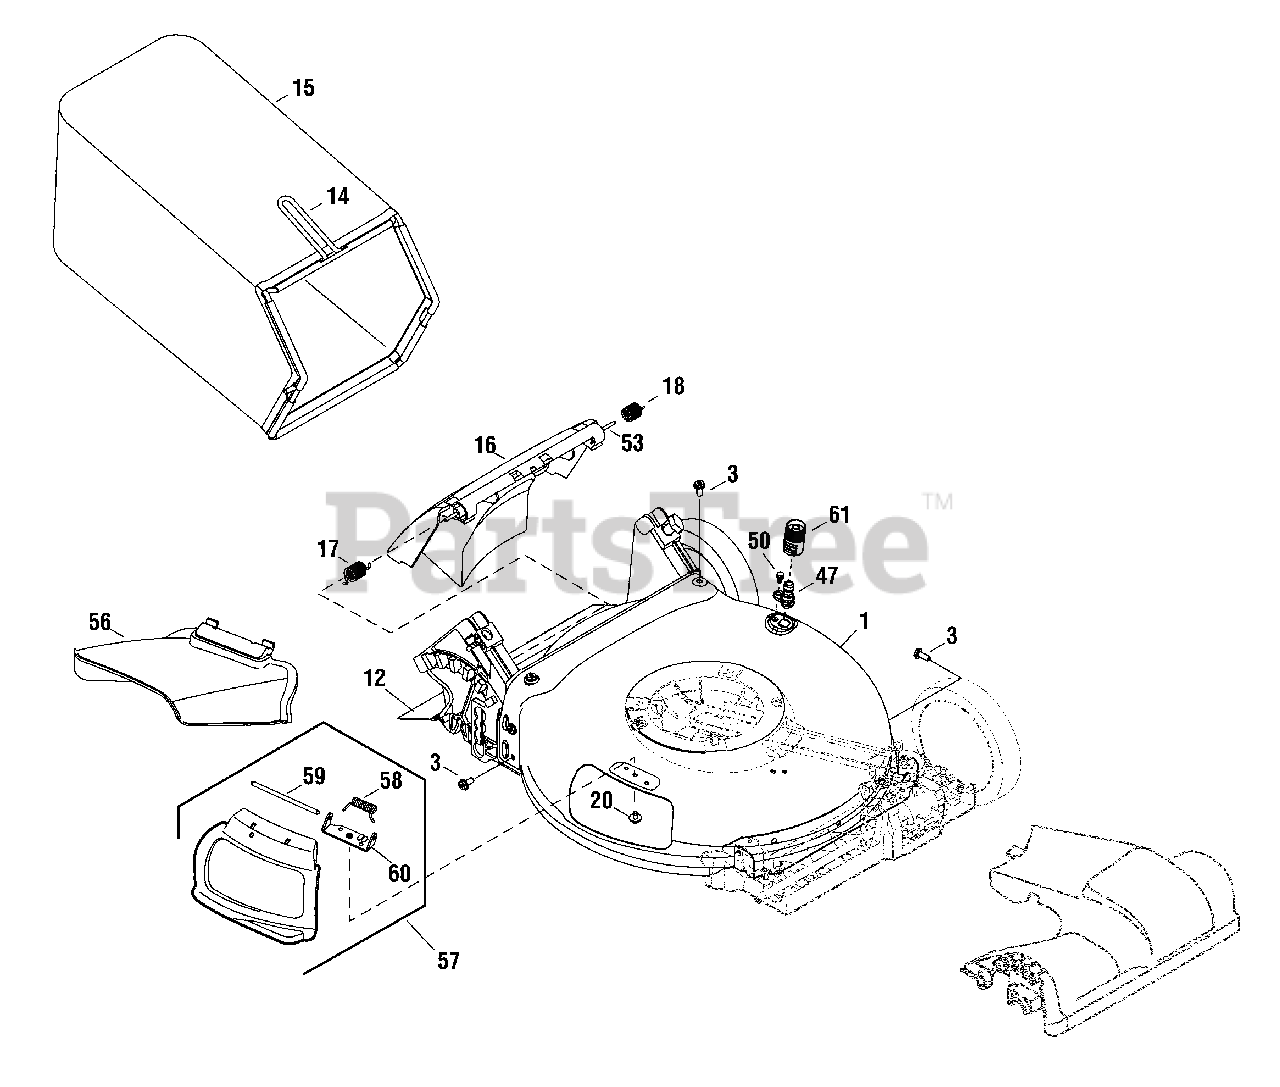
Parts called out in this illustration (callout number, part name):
3	SCREW, 5/16-14 x 3/4
12	SHIELD, Trailing
14	FRAME, Grass Bag
15	BAG, Grass
16	DOOR, Rear Discharge
17	SPRING, Torsion, RH
18	SPRING, Torsion, LH
20	SCREW, 1/4-20 x 1/2
47	NOZZLE, Water
50	BOLT, Shoulder, 1/4-20 x 1/2"
53	ROD, Pivot
56	CHUTE, Side Discharge
57	MULCH PLUG
58	SPRING, Torsion
59	PIN, Hinge
60	BRACKET, Chute Deflector
61	ADAPTER, Water Nozzle
